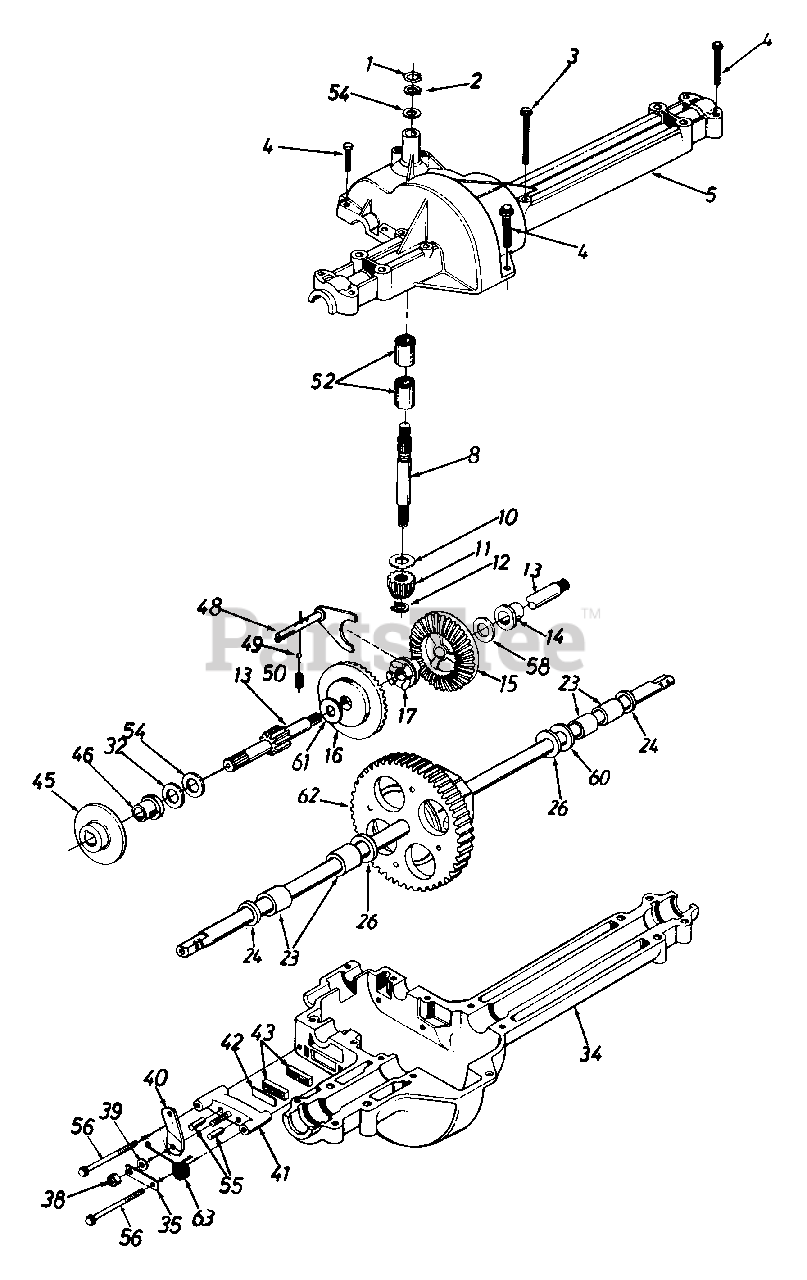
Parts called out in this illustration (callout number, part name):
1	Wire Ring
2	Retaining - Ring
3	Hex Wash. TT-Tap Scr, 1/4-20 x 1.75" Lg.
4	Hex Tap Scr. 1/4-20 x 1.25" Lg.
5	Upper Housing
8	Input Shaft
10	Thrust Washer 5/8" I.D. x 1.25" O.D.
11	Pinion Input 14T
12	Retaining Ring
13	Drive Shaft - L.H. Brake
14	Flange Brg. 5/8" I.D. x 3/4" Lg.
15	Bevel Gear 42T Small I.D.
16	Bevel Gear 42T Large I.D.
17	Clutch Collar
23	Sleeve Bearing 3/4" I.D. x 1.0" Lg.
24	Oil Seal 3/4" I.D.
26	Fl-Wash. .760" I.D. x 1.5" O.D.
32	Washer
32	Thrust Wash. 5/8" I.D. x 1" O.D. x .025" Thk.
32	Fl-Wash. 5/8" I.D. x 1" O.D. x .030" Thk.
32	Thrust Wash. 5/8" I.D. x 1" O.D. x .035" Thk.
32	Fl-Wash. 5/8" I.D. x 1" O.D. x .040" Thk.
34	Lower Housing
35	Anti-Rotation Brkt.
38	Hex Nut 5/16-24 Thd.
39	Fl-Wash. .344" I.D. x .875" O.D.
40	Actuating Arm
41	Brake Yoke
42	Puck Plate
43	Brake Puck
45	Brake Disc
46	Flange Bearing 5/8" I.D. x 15/16" Lg.
48	Shift Fork Ass'y.
49	Ball Detent .250" Dia.
50	Spring Detent
52	Needle Brg. 5/8" I.D. x 1/2" Lg.
54	Fl-Wash. 5/8" I.D. x 1" O.D. x .020 Thk.
55	Actuating Pin 5/16" Dia.
56	Hex Wash Hd. Self-Tap Scr. 1/4-20 Thd.
58	Fl-Wash. 5/8" I.D. x 1" O.D. x .020 Thk.
60	Washer
60	Fl-Wash. .76" I.D. x 1.5" O.D. x .010" Thk.
60	Fl-Wash. .76" I.D. x 1.5" O.D. x .020" Thk.
60	Fl-Wash. .76" I.D. x 1.5" O.D. x .030" Thk.
60	Fl-Wash. .76" I.D. x 1.5" O.D. x .060" Thk.
61	Thrust Washer
62	Differential Ass'y.
63	L.H. Brake Spring
